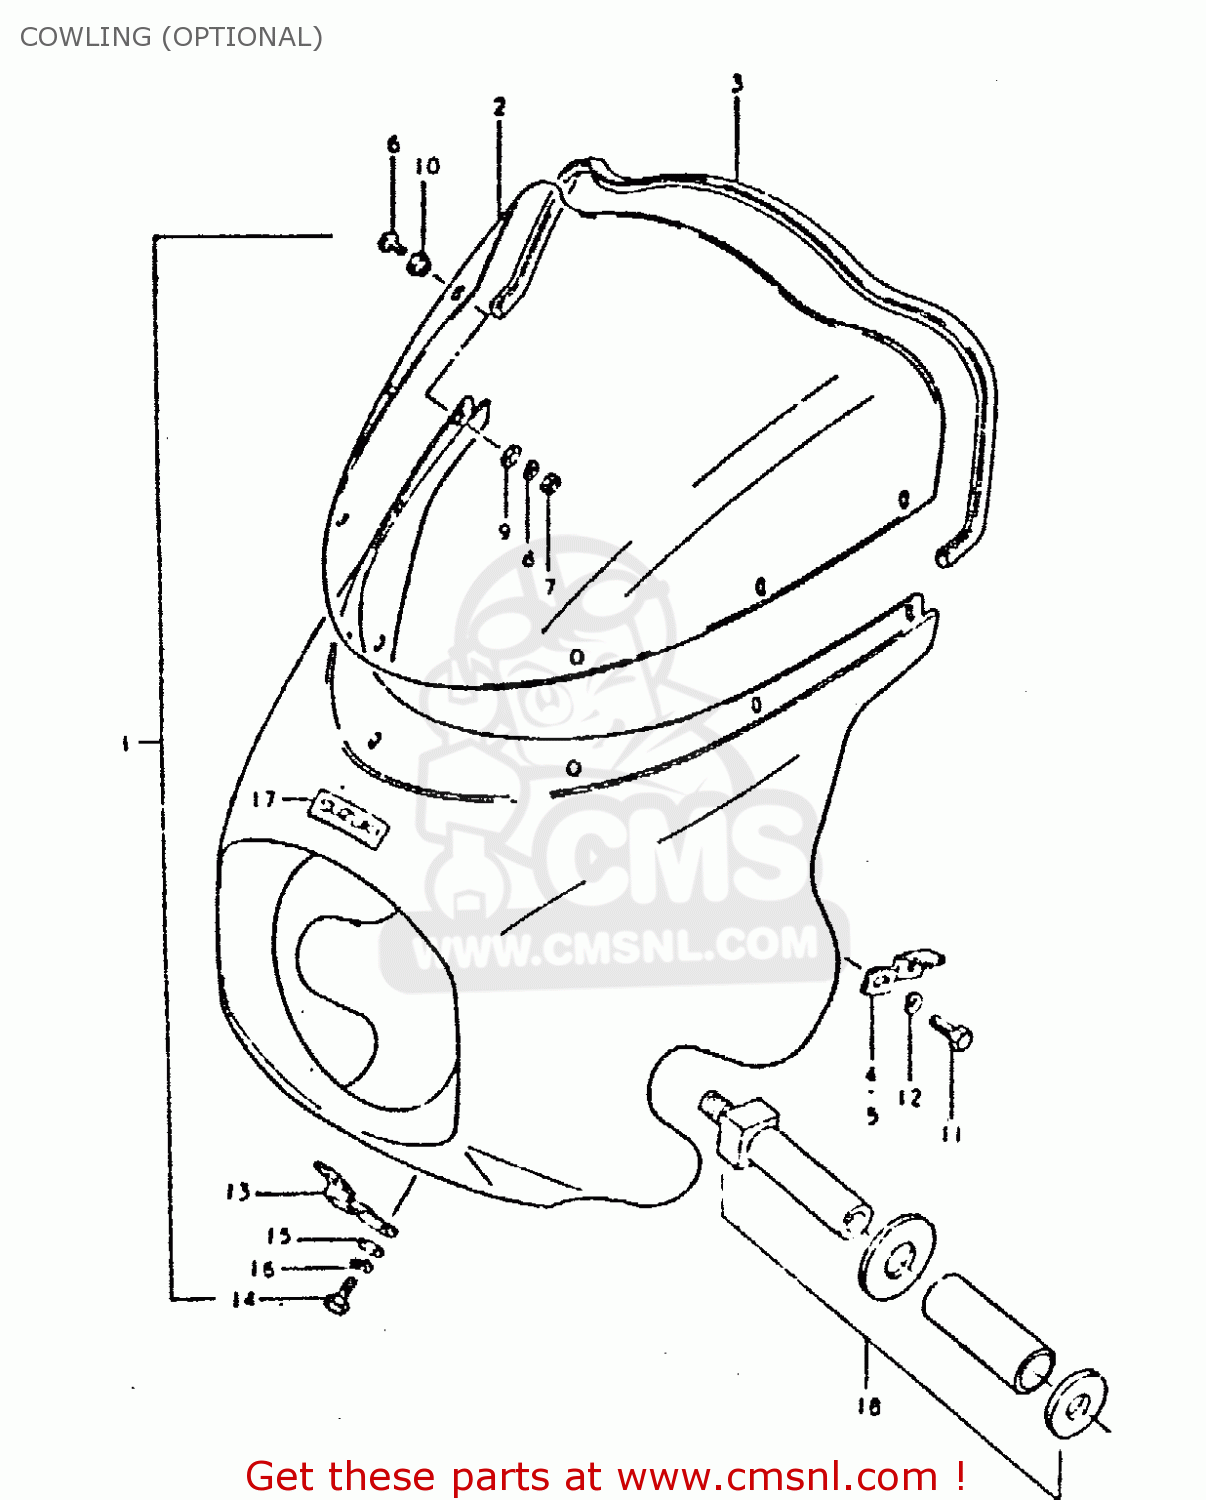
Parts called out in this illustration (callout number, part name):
1	COWLING ASSY
2	WINDOW, COWLING
3	MOLDING,COWLING
4	BRACKET,COWLING,RIGHT
5	BRACKET, LH
6	SCREW
7	NUT
8	LOCK WASHER
9	WASHER
10	CUSHION
11	BOLT
12	LOCK WASHER
13	BRACKET,COWLING,LOWER
14	BOLT
15	WASHER
16	LOCK WASHER
17	EMBLEM
18	TURN SIGNAL, EXTENTION
